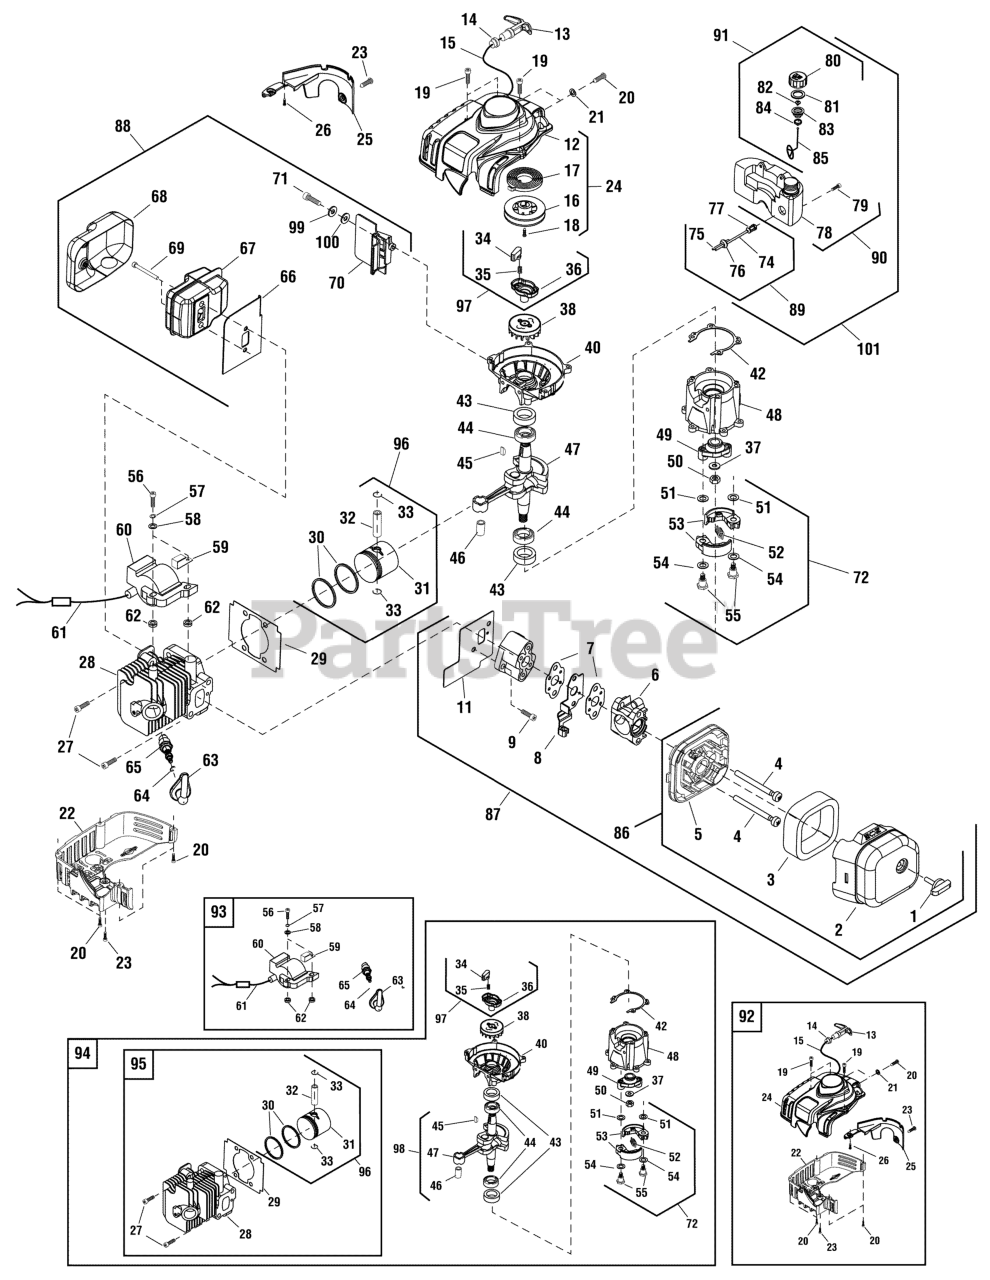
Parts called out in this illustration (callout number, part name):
1	BOLT, Big Head
2	COVER, Cleaner, Outer
3	AIR CLEANER
4	BOLT, M5 x 55
5	COVER, Cleaner, Inner
6	CARBURETOR
7	GASKET, Carburetor
8	BRACKET, Cable
9	BOLT, M5 x 16
10	ADMITTING PIPE
11	GASKET, Admitting Pipe
12	SHROUD, Top
13	HANDLE, Starter
14	GUARD, Cord
15	CORD, Starter
16	WHEEL, Starter
17	SPRING, Starter
18	SCREW, Self Tapping
19	BOLT, M5 x 20
20	SCREW, Self Tapping, ST4.2 x 16-F
21	WASHER, Flat, 0.4
22	SHROUD, Bottom
23	BOLT, M5 x 12
24	KIT, Shroud, Upper
25	Inner Air Flow Wall
26	BOLT, M5 x 8
27	BOLT, M5 x 20
28	CYLINDER HEAD
29	GASKET, Cylinder
30	PISTON RING
31	PISTON
32	PIN, Piston
33	RETAINING RING, Pin
34	CLINCH, Starter
35	SPRING, Starter
36	START REEL
37	WASHER, Flat, 8
38	FLYWHEEL
39	BOLT, M5 x 25
40	CRANK CASE, Front
41	PIN, Cylindrical, B3 x 10
42	GASKET, Crank Case
43	SEAL, Oil, 11.7 x 22 x 7
46	BEARING
47	CRANK SHAFT
48	CRANK CASE, Rear
49	PLATE, Clutch
50	NUT, Hex, M8 x 1
51	WASHER, Flat
52	SRPING, Extension
53	EXPANDER
54	WASHER, Wave
55	SCREW, Shaft
56	BOLT, M4 x 20
57	WASHER, Spring, 4
58	WASHER, Flat, 4
59	CLAMP, Wire
60	MAGNETO COIL
61	CORD, Complete
62	INSULATOR
63	BOOT, Spark Plug
64	CLIP, Spark Plug
65	SPARK PLUG
66	GASKET, Muffler
67	MUFFLER
68	GUARD, Muffler
69	BOLT, M5 x 55-10.9
70	PROTECT PIECE, Muffler
71	BOLT, M4 x 16
72	KIT, Expander
74	LINE, Fuel
75	PIPE, Fuel
76	PLUG
77	FILTER, Fuel
78	TANK, Fuel
79	BOLT, M5 x 16
80	CAP, Fuel Tank
81	GASKET
82	INLET
83	LID, Fuel Tank, Inner
84	COVER, End
85	CHAIN
86	KIT, Air Cleaner
87	AIR INTAKE ASSEMBLY
88	KIT, Muffler
89	KIT, Fuel Line
90	KIT, Fuel Tank
91	KIT, Fuel Cap
92	KIT, Shroud, Upper & Lower
93	KIT, Magneto Coil
94	KIT, Cylinder Assembly
95	KIT, Cylinder Head
96	KIT, Piston
97	KIT, Start Reel
98	KIT, Crank Shaft
99	WASHER, Spring, 4
100	WASHER, Flat, 4
101	KIT, Fuel Tank
